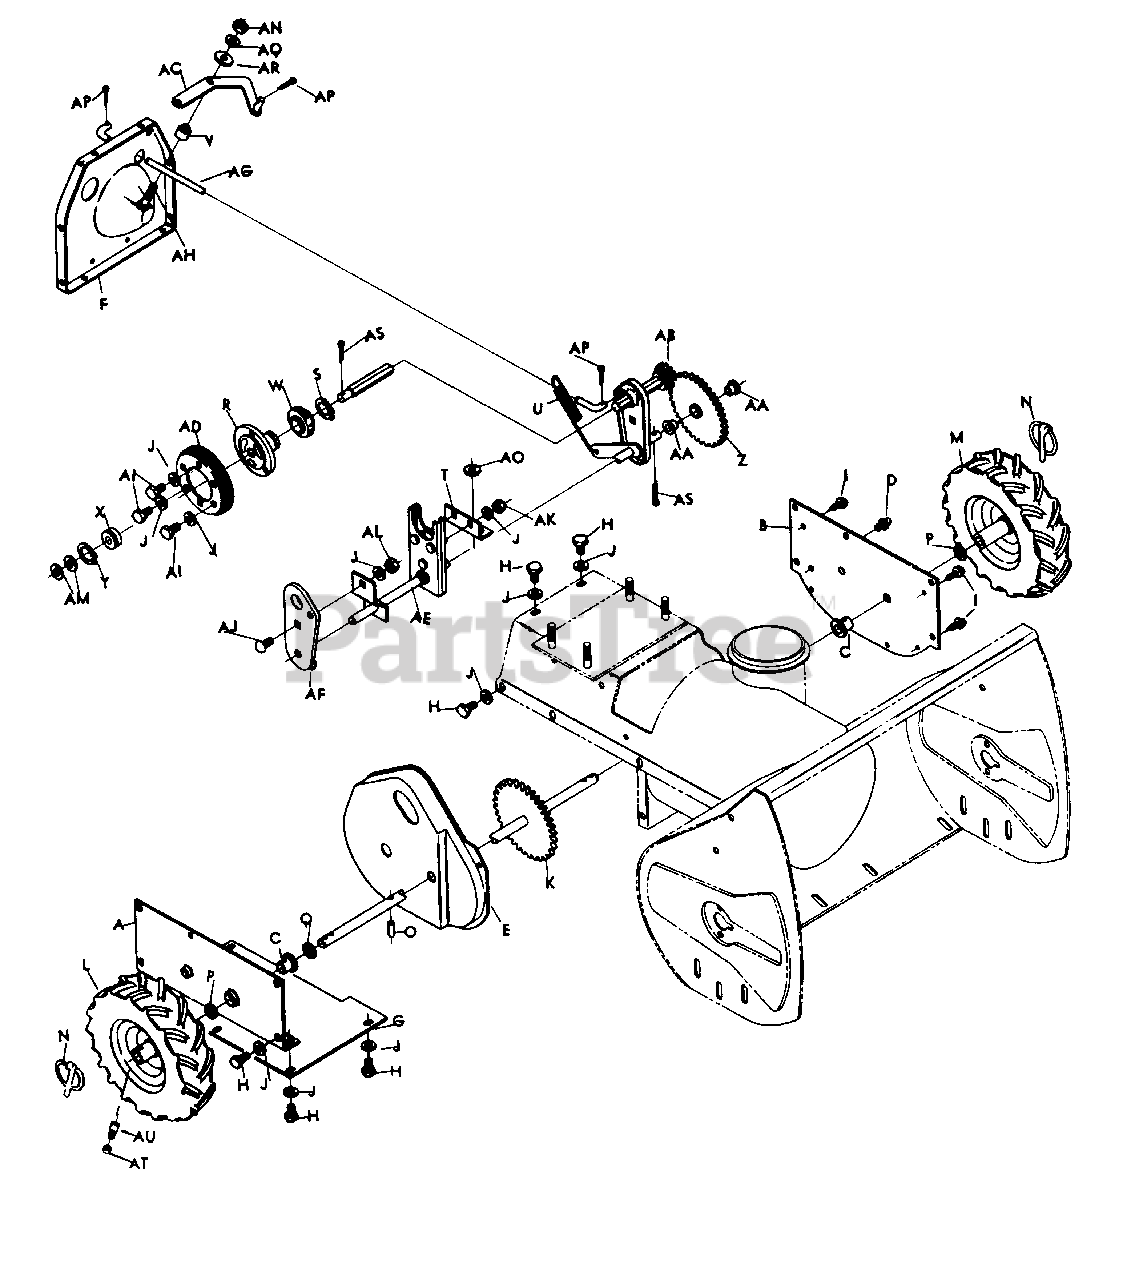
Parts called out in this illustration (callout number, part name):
A	Main Frame Ass'y-Lower w/Bearing
B	Main Frame Ass'y-Lower w/Bearing
C	Axle Bearing
D	Grease Fitting
E	Gear Case Cover
F	Backing Plate Assembly
G	Inspection Cover
H	5/16-18 x 3/4 Hex Hd. Capscrew-Pl.
I	No. 10 x 1/2 Hex Hd. Type "A" Sheet Metal Scr
J	5/16 Lockwasher-Pl.
K	Axle Assembly
N	Klik Pin
O	1/8 x 1 1/4 Roll Pin
P	Washer
Q	Washer
R	Friction Wheel Hub
S	Retaining Ring
T	Shifter Slide
U	Spring
V	Pivot Bushing
W	Bearing
X	Bearing
Y	Retaining Ring
Z	Countershaft Gear Assembly
AA	Bushing
AB	Traction Drive Shaft Assembly
AC	Bellcrank Assembly
AD	Friction Wheel Roller
AE	Traction Drive Support Arm Ass'y
AF	Traction Drive Support Arm
AH	3/8-16 x 1 3/4 Hex Hd. Capscrew-Pl.
AI	5/16-18 x 1/2 Hex Hd. Capscrew-Pl.
AJ	5/16-18 x 1/2 Carriage Bolt-Pl.
AK	5/16-18 Hex Cone Locknut-Pl.
AL	5/16-18 Hex Nut-Pl.
AM	Washer
AN	3/8-16 Cone Locknut-Pl.
AO	5/16 SAE Flat Washer
AP	1/8 x 3/4 Cotter Pin-Pl.
AQ	3/8 Lockwasher-Pl.
AR	Washer
AS	1/8 x 1 Cotter Pin-Pl.
AT	Valve Cap
AU	Valve Stem
